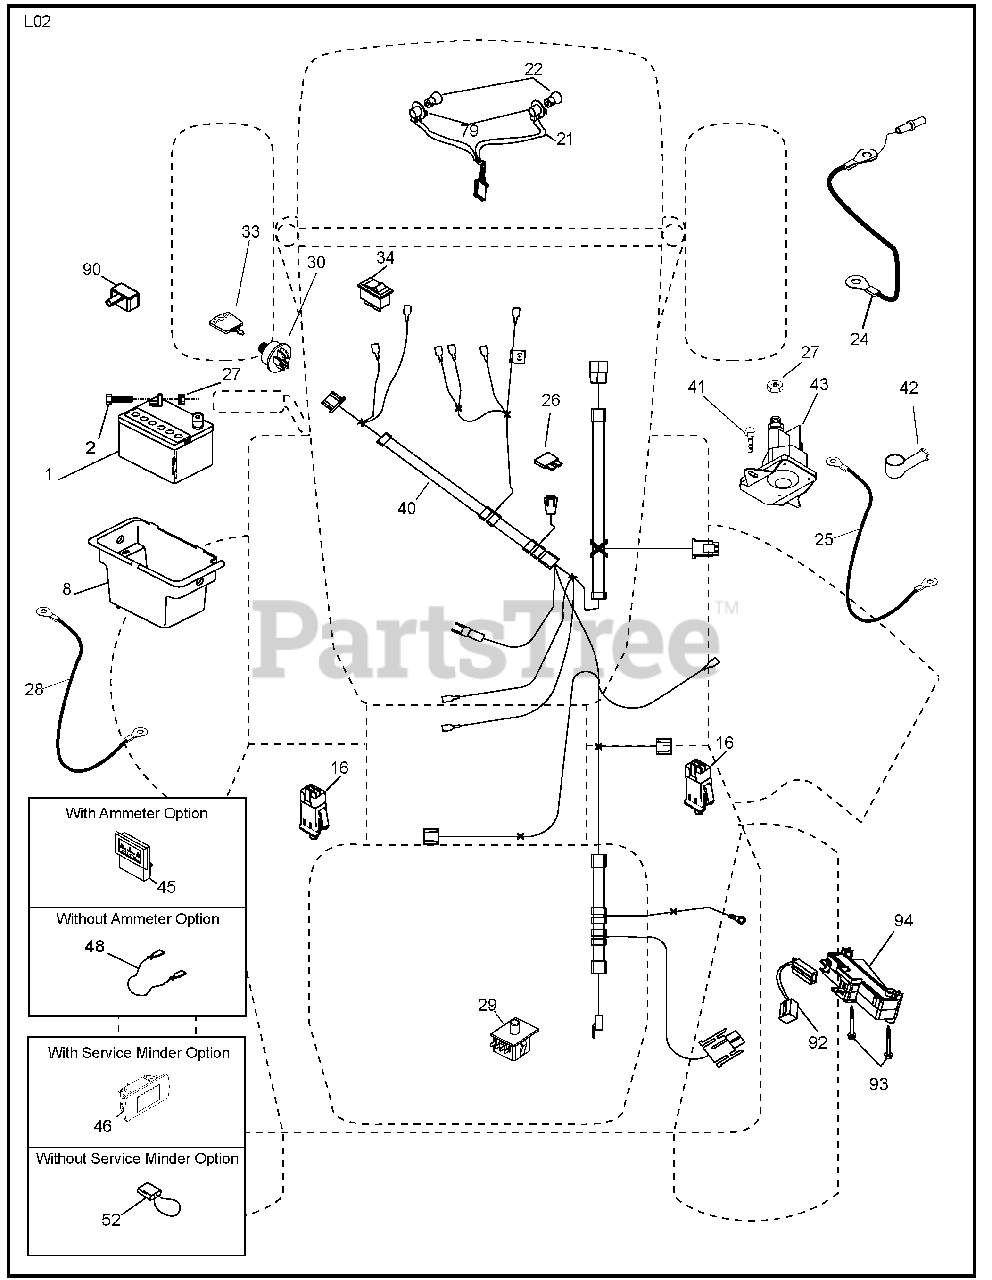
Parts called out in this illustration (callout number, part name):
1	Battery
2	Bolt Hex Hd 1/4-20 unc x 3/4
8	Box Battery
16	Switch Interlock
21	Harness Asm Light W/4152j
22	Bulb Light #1156
24	Cable Battery 6 Ga. 11"Red
25	Cable Battery
26	Fuse 20 AMP
27	Nut Keps Hex 1/4-20 unc
28	Cable Ground 6 Ga. 12" Black
29	Switch Seat
30	Switch Ign
33	Key/Chain
34	Switch Light/Reset
40	Harness Ign
41	Bolt Blk Fin Hex 1/4-20
42	Cover Terminal Red
43	Solenoid
48	Adapter Ammeter
52	Protection Wire Loop
79	Socket Asm. Bulb Twistlock
90	Cover Terminal Battery
92	Harness Pigtail
93	Screw Plastite 10-14 x 2.0
94	Module Reverse ROS
